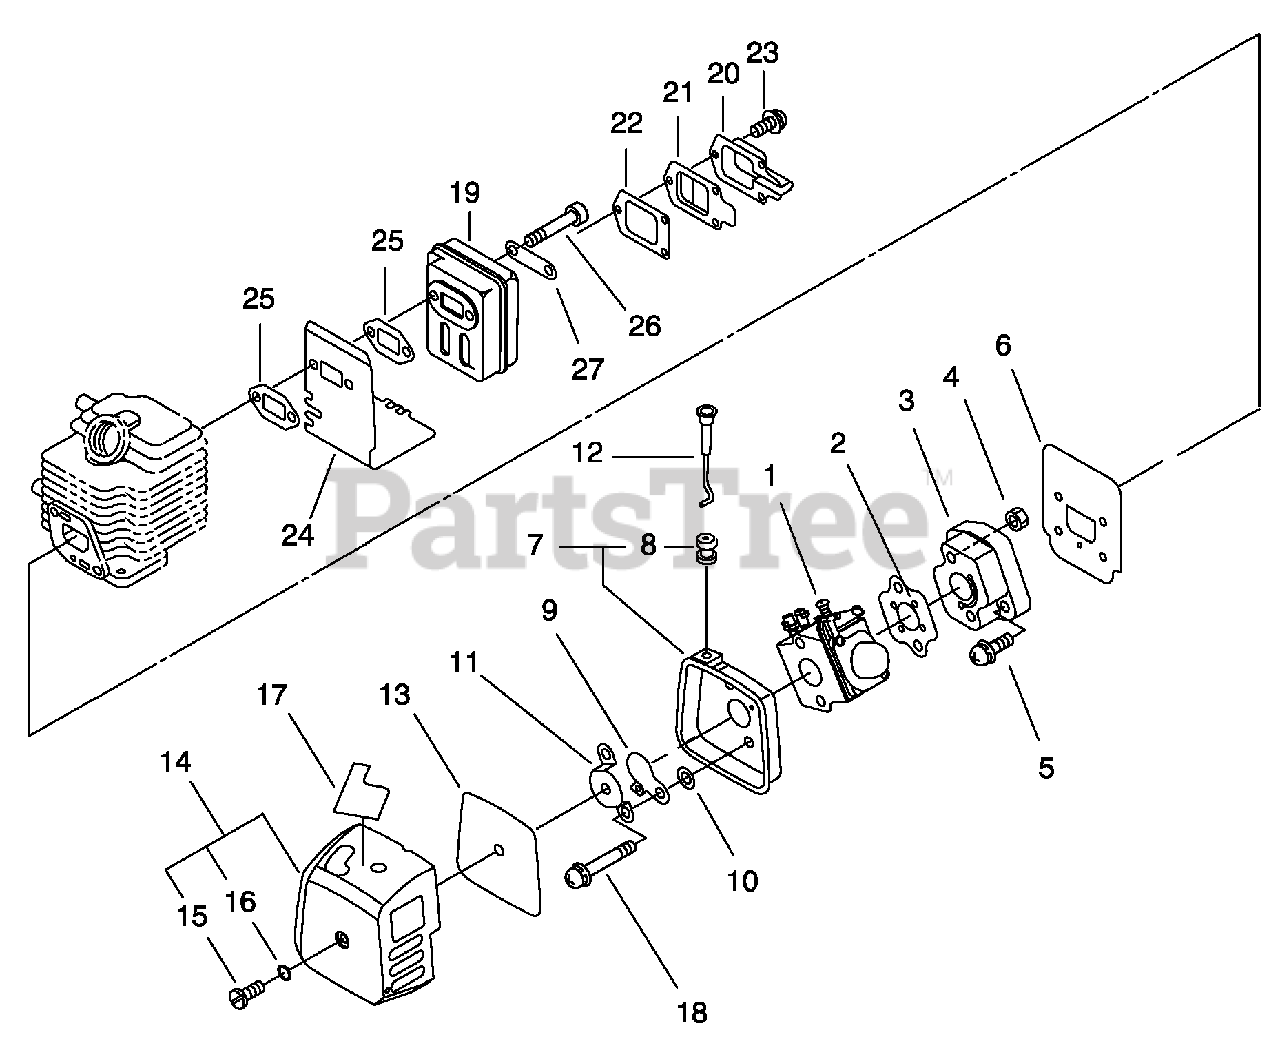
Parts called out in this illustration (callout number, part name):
1	CARBURETOR
2	GASKET, INTAKE
3	INSULATOR, INTAKE
4	NUT M5
5	SCREW 5×20
6	HEAT SHIELD, INTAKE
7	CASE, AIR FILTER
8	GROMMET, CHOKE
9	SHUTTER, CHOKE
10	WASHER 5.2×8×0.8T
11	CASE, AIR FILTER
12	ROD, CHOKE
13	FILTER, AIR
14	AIR FILTER COVER ASSY
17	LABEL, CHOKE
18	SCREW 5×57
19	MUFFLER
20	GUIDE, EXHAUST
21	GUIDE, EXHAUST
22	GASKET, EXHAUST
23	SCREW 4×10
24	HEAT SHIELD, EXHAUST
25	GASKET, EXHAUST
26	BOLT 5×55
